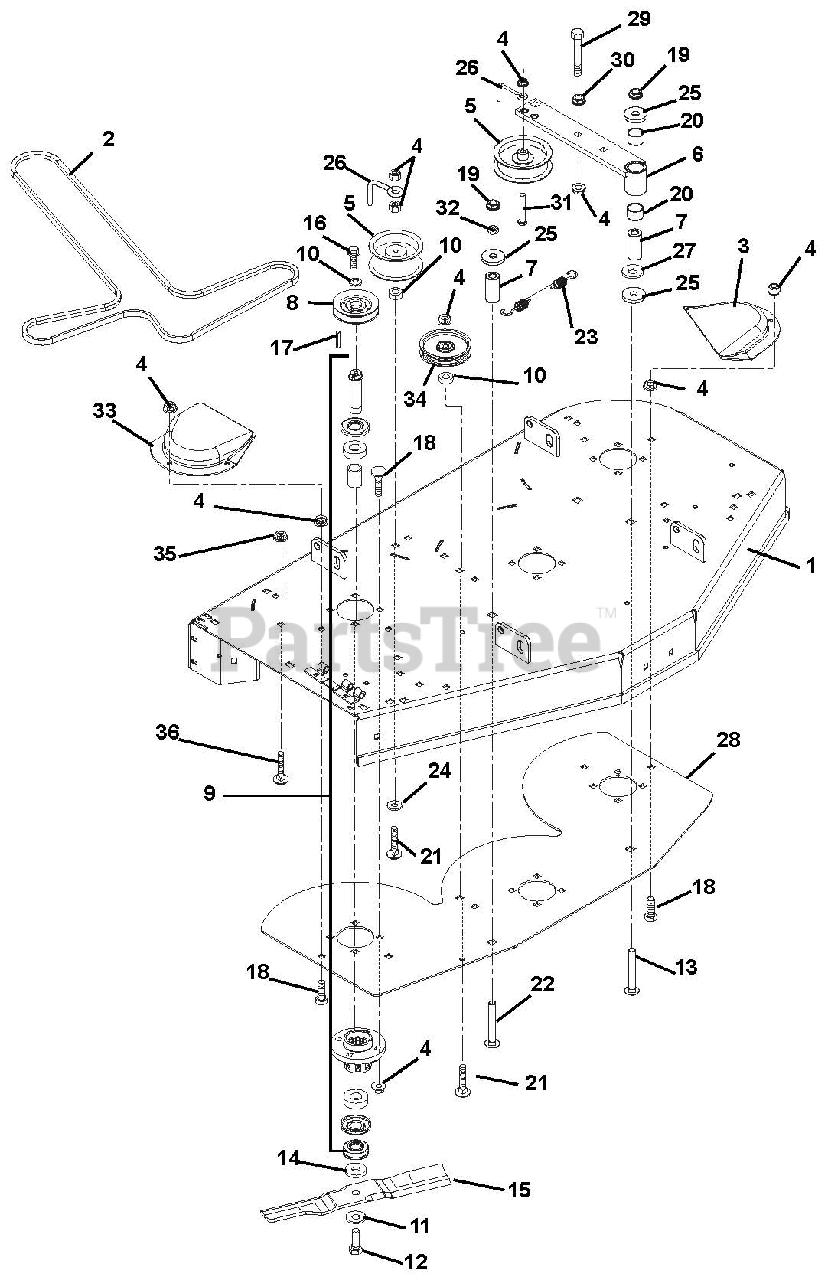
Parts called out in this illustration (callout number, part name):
1	Weldment 40" Deck
2	V-Belt, HA x 112.3 EFF.
4	Nut .38-16 Flange Nyloc
5	Pulley, Idler 4.00
6	Weldment, Idler Arm
7	Spacer, Powdered Metal
8	Sheave, Spindle 4.00 Dia.
9	Assembly, Spindle
10	Washer, Flat Steel .406 x 1.50 x .245
11	Washer, Beveled .63 x 1.625 x .140
12	Bolt, Hex .62-18 x 1.75 Grade 8
13	Bolt, Round Head Square Neck .50-13 x 3.50 Grade 5
14	Washer, Flat .Steel .688 x 1.75 x .134
15	Blade, Mower (13.88)
16	Bolt, Hex .38-16 x 1.00 Grade 8 with Epoxy Patch
17	Key, Square .25 x .38 x .25
18	Bolt, Round Head Square Neck .38-16 x 1.25
19	Nut, Locking Top Flange .50-13
20	Bearing, 1.00 x 1.12 x .75
21	Bolt, Round Head Square Neck .38-16 x 2.00 Grade 5
22	Bolt, Round Head Square Neck .50-13 x 3.75 Grade 5
23	Spring, Extension .187 x 1.50 x 9.94
24	Washer, Flat Steel .531 x 1.06 x .095
25	Washer, Flat Steel .515 x 1.625 x .25
26	Finger, Belt
27	Washer, Flat Steel .511 x 1.44 x .125
28	Plate, 40" Doubler
29	Bolt, Hex .38-16 x 2.00
30	Nut, Spinlock Flange .375-16
31	Bolt, Hex .38-16 x 2.50
32	Nut, Spinlock Flange .50-13
33	Belt Cover
34	Idler, Flat .38 x 4.00 x 1.06
35	Nut, Flange Nyloc 5/16-18
36	Bolt, Round Head Square Neck .31-18 x .62
